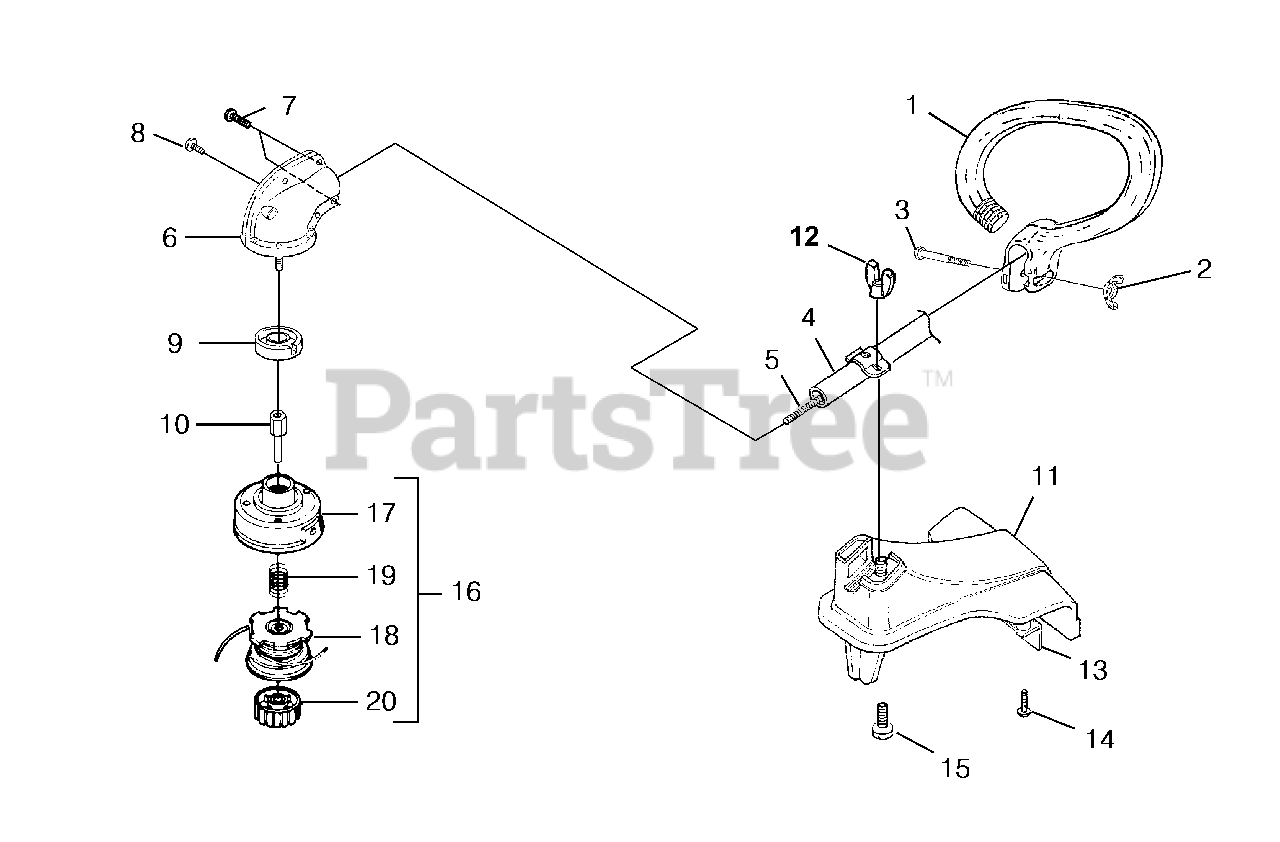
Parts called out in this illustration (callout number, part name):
1	HANDLE-Anti-Vibe
2	NUT-Wing, Washer Faced (1/4-20)
3	SCREW-Cap Hex Hd.
4	DRIVESHAFT ASSY.
4	DRIVESHAFT ASSY. (UT20832)
5	SHAFT-Flexible
6	GEARHEAD
7	Screw-Hex Hd. (10-24 x 5/8")
8	Screw, Taptite Hex Hd. (10-24 x 1/2")
9	WASHER-Flanged
10	ADAPTER-Shaft
11	GRASS DEFLECTOR KIT
12	WING NUT
13	BLADE-Cut-off
14	SCREW-Plastite. (10-14 X 3/4")
15	SCREW-Square Head
16	STRINGHEAD-Complete (.080")
17	HOUSING & EYELET (Dual Line)
18	SPOOL & STRING (.080")
19	SPRING-Compression
20	RETAINER-Spool (R.H. Thread, Black)
